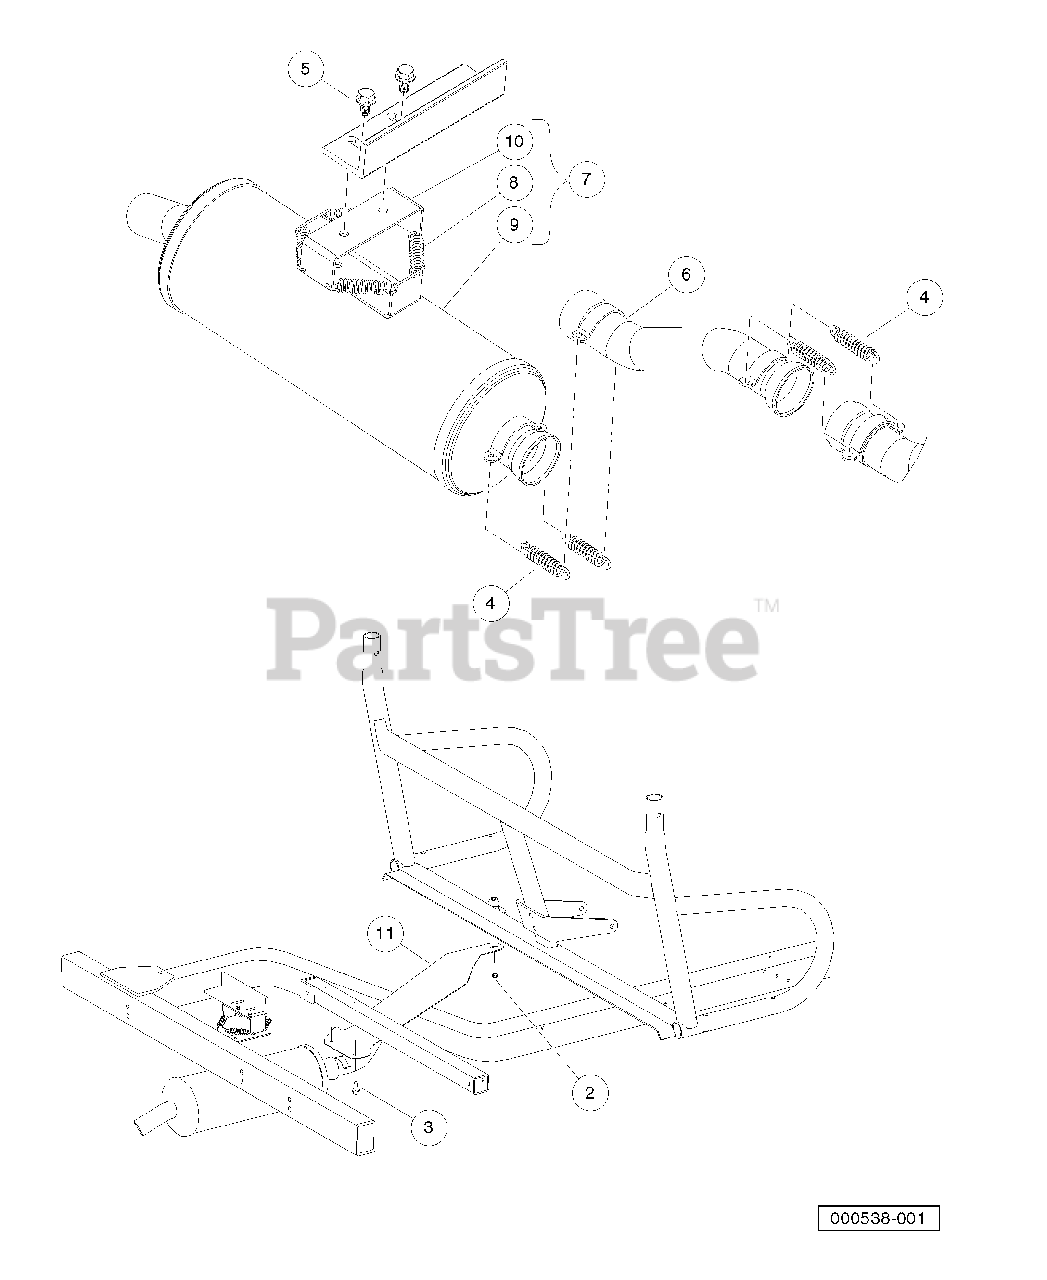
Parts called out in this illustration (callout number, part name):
1	Instl, Exhaust, AWD
2	Locknut, M6-1.00 Nylon Insert
3	M8-1.25x20 Taptite
4	Spring, Exhaust
5	Bolt Flanged Head, M8 X1.25x 16 with Loctite
6	Pipe, Exhaust, Int, Offset
7	Asm, Muffler, AWD Homologation
8	Spring, Exhaust
9	Muffler
10	Bracket, Muffler
11	Shield, Exhaust, Clearance
